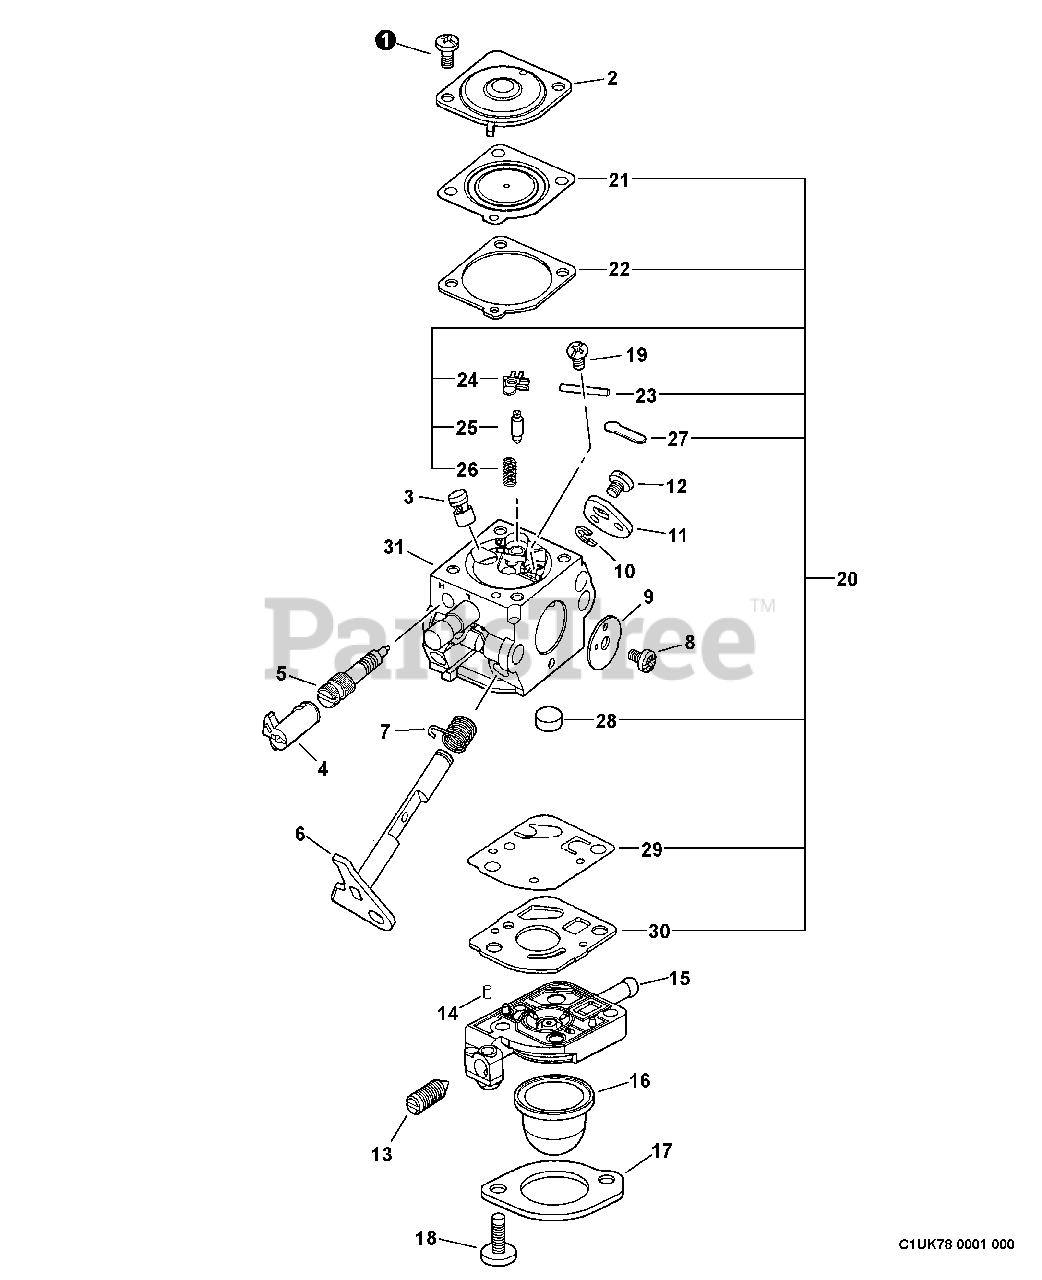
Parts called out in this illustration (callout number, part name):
2	COVER, METERING
3	NOZZLE, CHECK VALVE
4	CAP, LIMITER
5	NEEDLE - HIGH SPEED
6	SHAFT, THROTTLE
7	SPRING, RETURN
9	VALVE, THROTTLE
10	RING, RETAINING
11	LEVER, THROTTLE
13	SCREW, IDLE ADJUST
14	PIECE, FRICTION
15	BASE, PURGE
16	BULB, PURGE
17	RETAINER, PURGE BULB
18	SCREW, RETAINER
19	SCREW, METERING LEVER PIN
20	REPAIR KIT
21	DIAPHRAGM, METERING
22	GASKET, DIAPHRAGM
23	PIN, METERING LEVER
24	LEVER, METERING
25	VALVE, INLET NEEDLE
26	SPRING, METERING LEVER
27	PLUG, WELCH
28	STRAINER
29	DIAPHRAGM, PUMP
30	GASKET, PUMP
31	BODY, CARBURETOR
